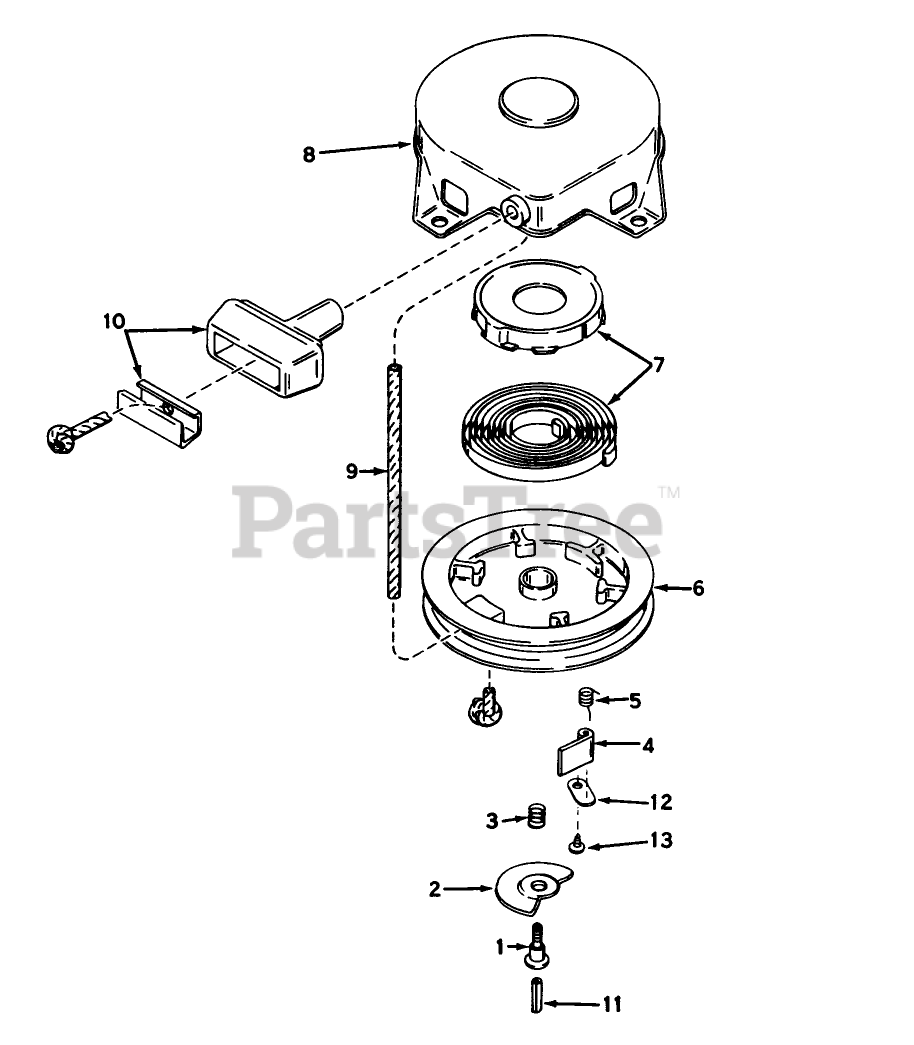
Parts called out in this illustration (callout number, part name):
1	Screw
2	Cam-Dog
3	Spring-Brake
4	Dog-Starter
5	Spring-Dog
6	Pulley
7	Spring Keeper Assy
8	STARTER HOUSING ASSY
9	Rope-Starter
10	Assy., Starter
11	Centering
12	Retainer-Dog
13	Screw
